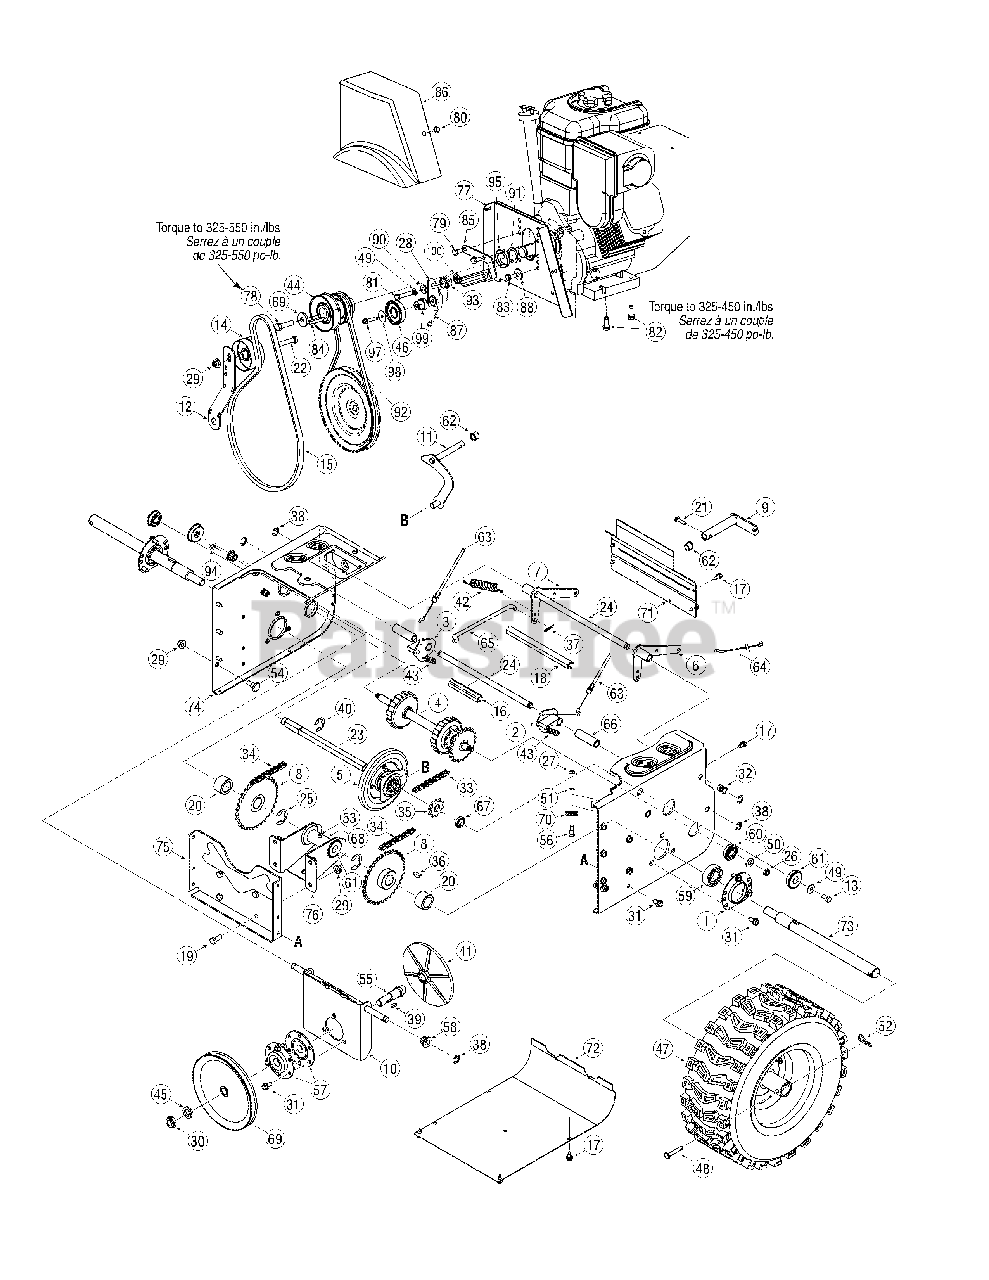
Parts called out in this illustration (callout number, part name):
1	Bearing Housing
2	LH Dog Assembly
3	RH Dog Assembly
4	Steering Shaft Assembly
5	Wheel Ass’y Bearing 6.0" OD
5	Friction Wheel Bonded
5	Hex Wash. Hd. TT Scr. 1/4-14 x .625
11	Shift Ass’y Rod
12	Auger Idler Bracket
13	Hex L-Bolt 5/16-18 x .62
14	Flat Idler Pulley
15	V-Belt 1/2 x 42" Lg.
16	Spacer .51 ID x 3.66" Lg.
17	Hex Wash Hd TT Scr. 1/4-20 x .625
18	Spacer .51 ID x 7.895" Lg.
19	Hex Hd. C-Sunk Scr. 3/8-16 x .880 Gr. 5
20	Spacer 1.0 ID x 1.5" Lg.
21	Hex Bolt 1/4-20 x 1.00
22	Hex Screw 3/8-16 x 1.75
23	Hex Drive Shaft
24	Ac tu a tor Shaft
25	Retaining Ring
26	Hex Nut 3/8-24
27	Hex Nut 1/4-28
28	Drive Idler Bracket
29	Flange L-Nut 3/8-16 Gr. F Nylon
30	Hex Jam Locknut 5/8-18 Gr. 5 Nylon
31	TT Screw, 5/16-18 x .75
32	Nut Insert 3/8-16 UNC
33	#41 Chain 1/2" pitch x 36 links- Endless
34	#420 Chain 1/2" pitch x 40 links-Endless
35	10T Sprocket #41 x .500
36	Woodruff Key
37	Int. Cotter Pin 5/16 DIA
38	E-ring
39	No. 61 Hi-Pro Key 3/16 x 5/8
40	Retaining Ring E-Type .875 dia.
41	Alumi num Drive Plate
42	Idler Extension Spring
43	Extension Spring .47 OD x 2.03 Lg.
44	Pulley, Dbl (w/342 cc engine)
44	Pulley, Dbl (w/305 cc engine)
45	Lockwasher 5/16 ID
46	Flat Idler Pulley 3.0 OD
47	Wheel Assembly 16 x 6.5 x 8 LH X-Trac
49	Cupped Washer .345 ID x .88 OD x .06
50	Flat Washer .385 ID x .87 OD x .06
51	L-Wash 1/4 ID
52	Int. Cotter Pin
53	Grease
54	Shld. Scr. .500 Dia. x .335" Lg.
55	Drive Plate Spindle
56	Hex Shld.Scr.1/4-28 x .375
57	Bearing Hsg. Ass’y.
58	Hex Flange Bearing
59	Self aligning brg. 1.0 ID
60	Ball Bearing .5625 ID x 1.3750 x .437
61	Ball Bearing w/snap ring
62	Flange Bushing .500 ID x .627 OD
63	Steering Cable
64	Auger Idler Cable
65	Drive Clutch Rod
66	Split Spacer 1/2 x 5/8 x 2.69
67	Spacer .625 ID x 1.0 OD x .23
68	Spacer .6725ID x 1.125 OD x 2.485
69	1/2" "V" Pulley .625 ID x 7.50 OD
70	Cable Guide Roller
73	Axle .995 x 12.6" Lg. (28")
73	Axle.995 x 14.10" Lg (30" & 33")
73	Axle .995 x 20.4" Lg. (45")
78	Hex Screw 3/8-24 x 1.5 Gr. 5
79	Hex Screw 5/16-24 x .625 Gr. 5
80	Hex Wash HD S-Tapp Scr 5/16-18 x .50
81	Hex HD. Cap Scr. 5/16-24 x 1.5 Lg. Gr. 5
82	Hex Wash HD Tap Scr 3/8-16 x 1.00
83	Hex Hd.Cap Scr. 5/16-24 x 0.75 Gr. 5
84	Square Key 1/4 x 1/4 x 1.50" Lg.
86	Belt Cover
87	Torsion Spring .850 x 3.33" Lg.
88	Shoulder Spacer .25 THK
89	Flat Washer .406 ID x 1.25 OD x .160
90	Shoulder Spacer .3175 x .5 x .094
91	Flat Washer 1.015 x 1.375 x .062
92	V-Belt 3/8 x 34.4" Lg.
93	Shoulder Spacer .340 x 1.0
94	Speed Nut .50
95	Spacer 1.004 x 1.375 x .25
97	Hex Bolt 1/4-20 x 1.25
98	Flat Washer .265 ID x 1.0 OD x 0.030 HT
99	Shoulder Spacer
